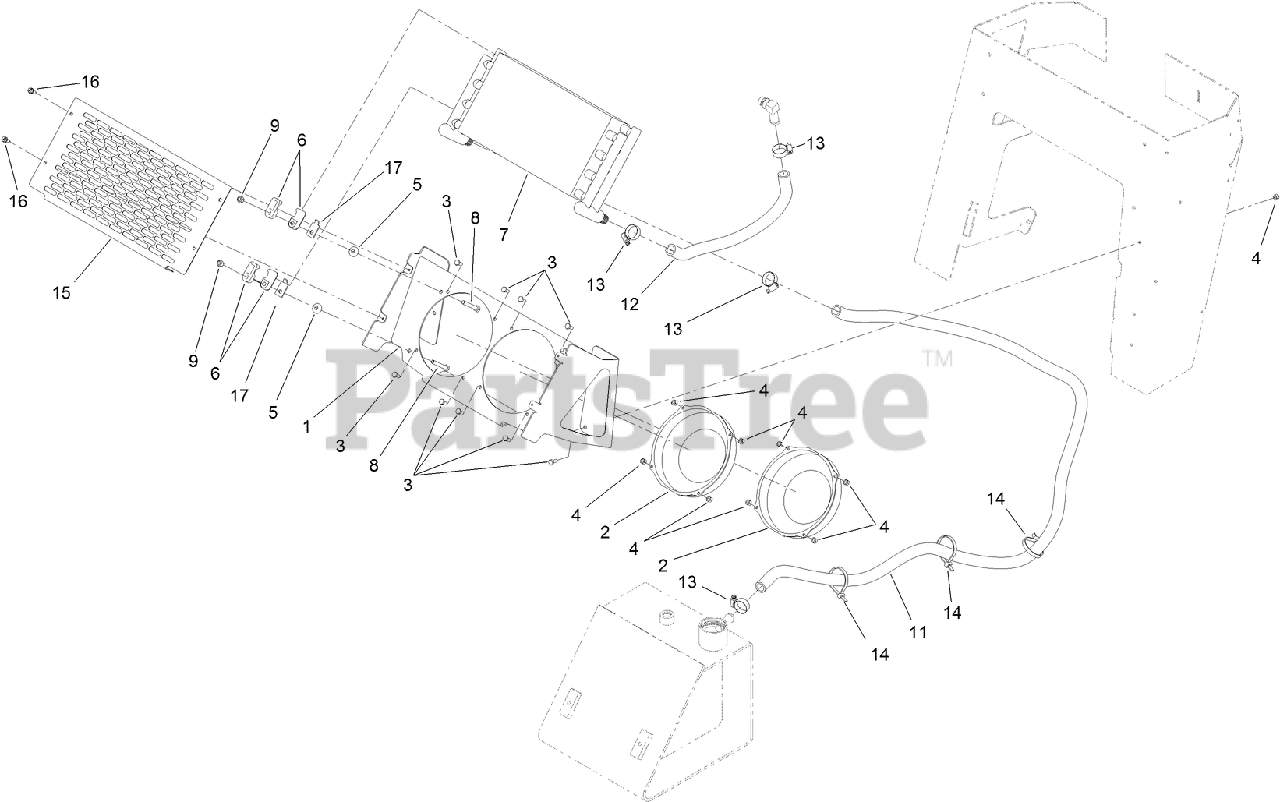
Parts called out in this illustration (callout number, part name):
1	MOUNT-COOLER
3	SCREW-HH
4	NUT-LOCK, NI
5	WASHER
7	COOLER-OIL
8	SCREW-HH
9	NUT-LOCK, NI
11	HOSE-RETURN
12	HOSE-COOLER
13	CLAMP-HOSE
14	TIE-CABLE
15	COVER-COOLER
16	SCREW-HWH
17	PLATE-SUPPORT, CLAMP
